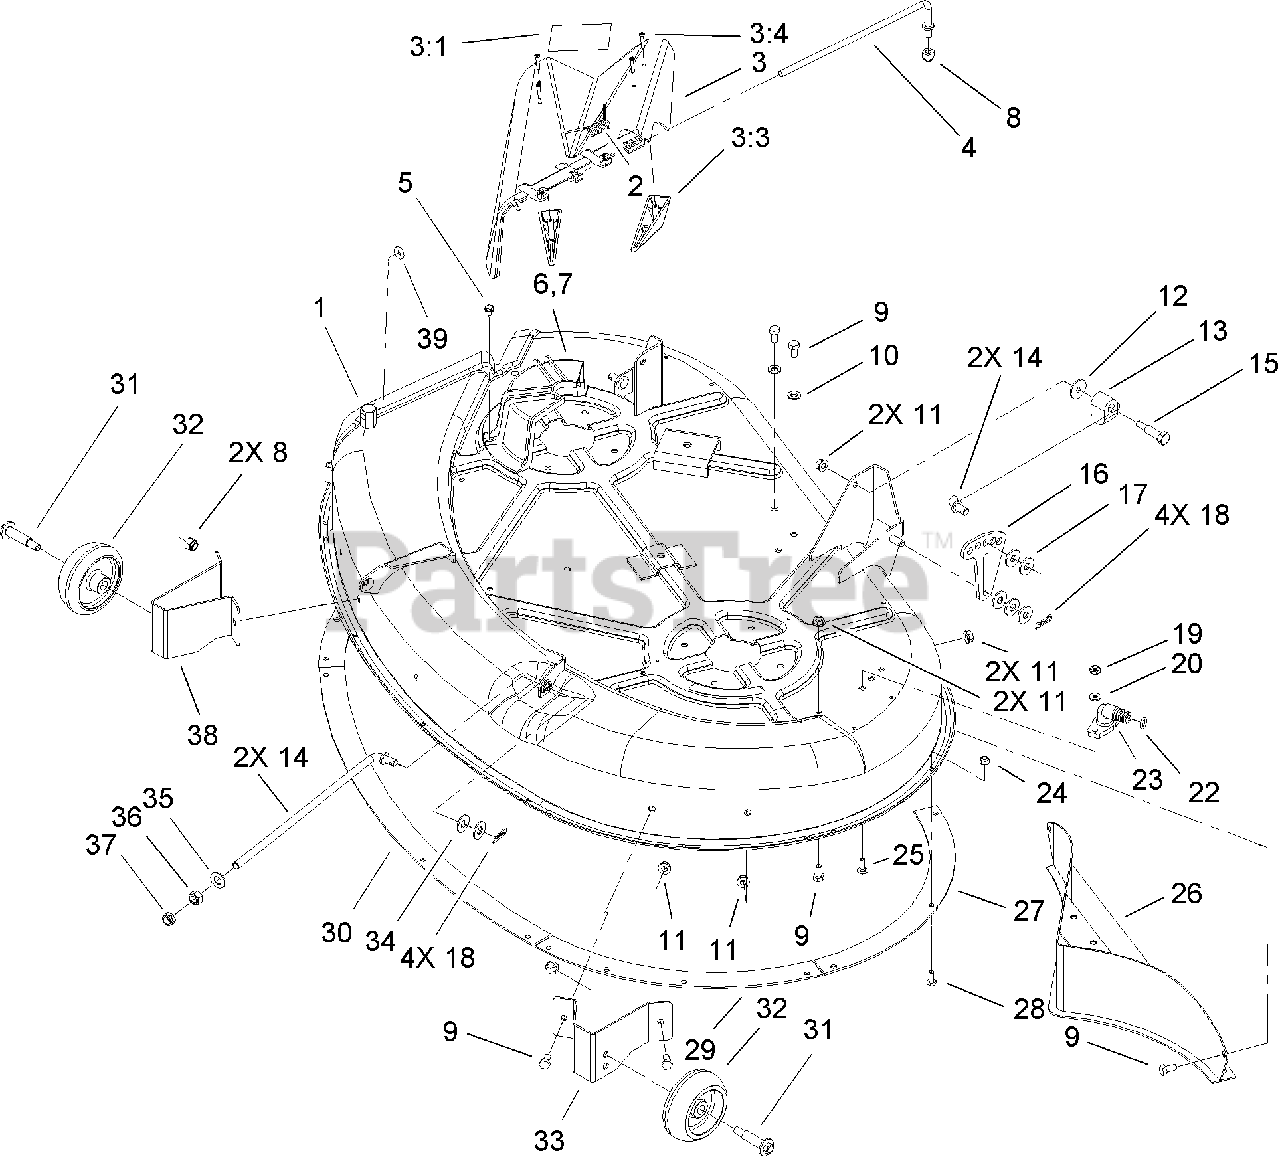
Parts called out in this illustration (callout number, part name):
1	42 IN DECK ASM
3	DEFLECTOR ASM
3:1	DECAL-DANGER
3:4	SCREW-PPH
4	ROD-PIVOT
7	RH BELT GUIDE-DECK
8	NUT-LOCK, NI
9	SCREW-HH
10	WASHER-FLAT
12	WASHER-PIVOT
13	TRUNNION-HOC
14	ROD-HANGER
15	BOLT-SHOULDER
16	LINK-ADJUSTING, HOC
17	WASHER-HARDENED
18	PIN-HAIR
19	NUT-LOCK, NI
20	WASHER-FLAT
23	FITTING-WASHOUT
24	NUT-LOCK, NI
25	SCREW-CARR
26	REAR BAFFLE ASM
27	RING-BLOW OUT, SIDE
28	SCREW-HH
29	RING-BLOW OUT, SIDE
30	RING-BLOW OUT
31	BOLT-WHEEL
32	WHEEL-GAGE
33	BRACKET-GAGE WHEEL, FRONT (LH)
34	WASHER-FLAT
35	WASHER-FLAT
36	NUT-HEX
37	NUT-LOCK, NI
38	BRACKET-GAGE WHEEL, FRONT (RH)
